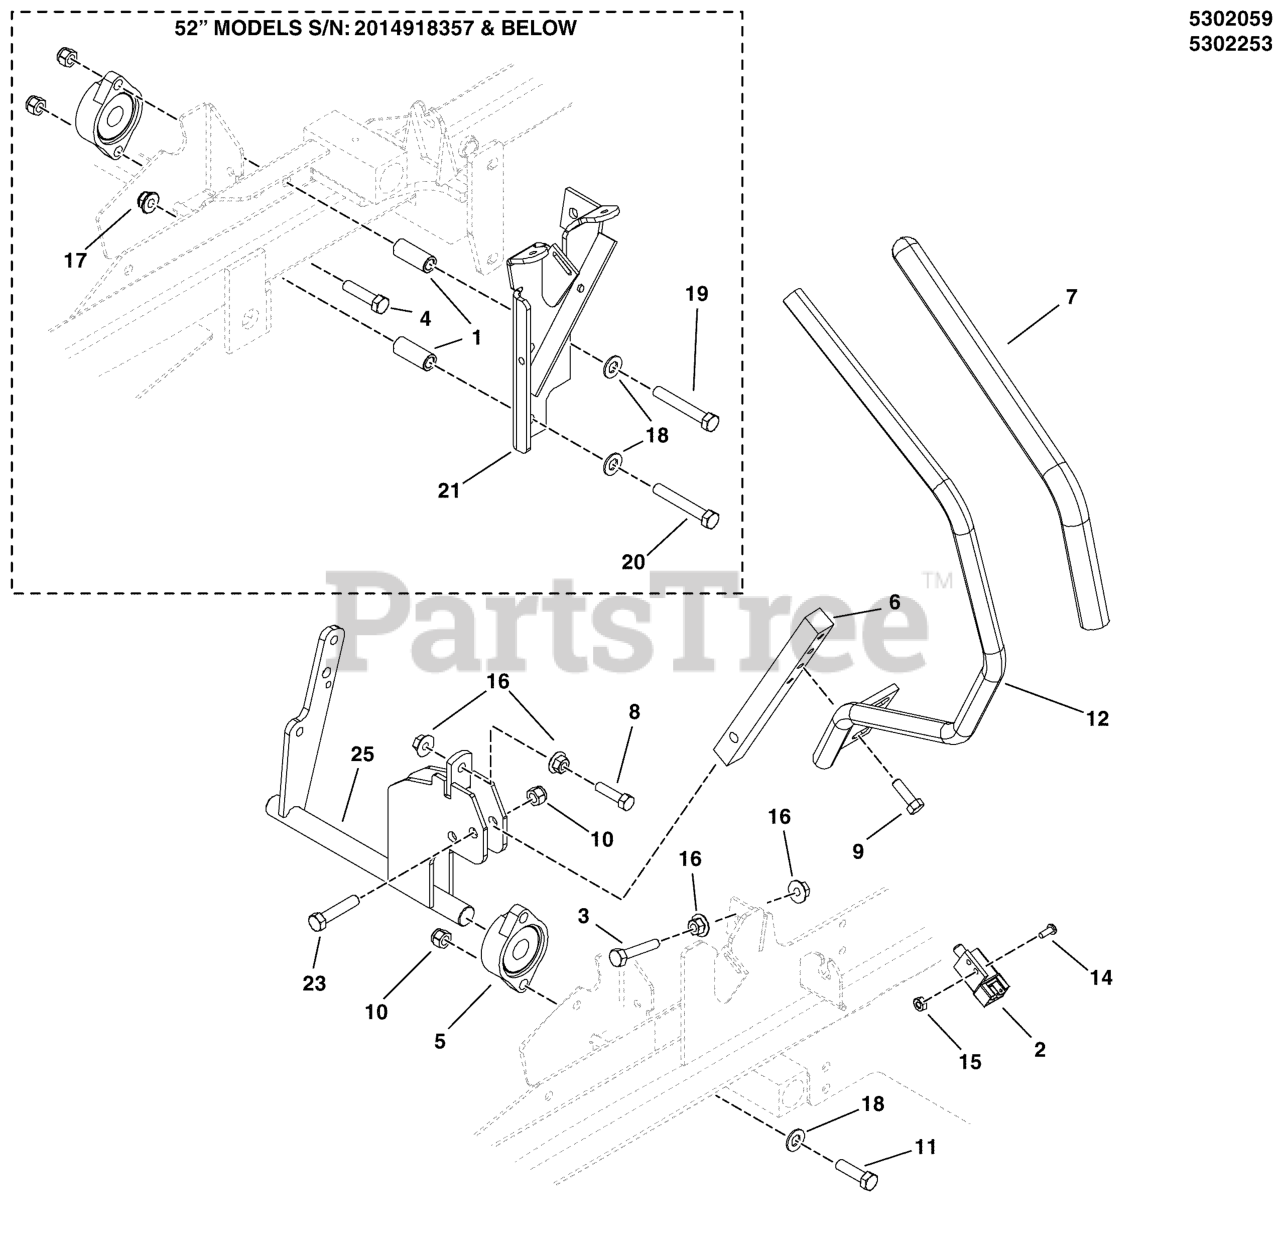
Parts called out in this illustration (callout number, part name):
1	SPACER, .39 X .63 X 1.50
2	SWITCH, PLUNGER, N.O.
3	BOLT- 5/16-18 X 1-1/2 GD5 TFL
4	BOLT, 3/8-16 X 1" GD5 CZ
5	BEARING, FLANGE
6	MOUNT, CONTROL ARM - BLK
7	GRIP, FOAM, 3/4 ID, 16 LONG
8	BOLT, 5/16-18 X 1-1/4 GD5 YZ
9	SCREW-HEX WSHR HD TAPTT5/16-18X0.750BLK
10	NUT, 3/8-16 HEX NYLON LOCK
11	BOLT, 3/8-16 X 1-1/4" GD5 CZ
12	WELD, HANDLE, MOTION CONTROL, LH - BLK
13	WELD, HANDLE, MOTION CONTROL, RH - BLK
14	SCREW- #10-24 X 1/2 ROUND PHILLIPS
15	NUT, #10-24 HEX
16	NUT, 5/16-18 HEX SERRATED FLANGE (LARGE)
17	NUT, 3/8-16 HEX NYLOCK FLANGE
18	WASHER, 3/8 SAE
19	BOLT, 3/8-16 X 3" GD5 CZ
20	BOLT, 3/8-16 X 2-1/2" GD5 CZ
21	WELD, NEUTRAL LOCK - LH - RED
22	WELD, NEUTRAL LOCK - RH - RED
23	BOLT, 3/8-16 X 1-3/4" GD5 CZ
24	WELD, CONTROL SHAFT - RH - BLK
25	WELD, CONTROL SHAFT - LH - BLK
